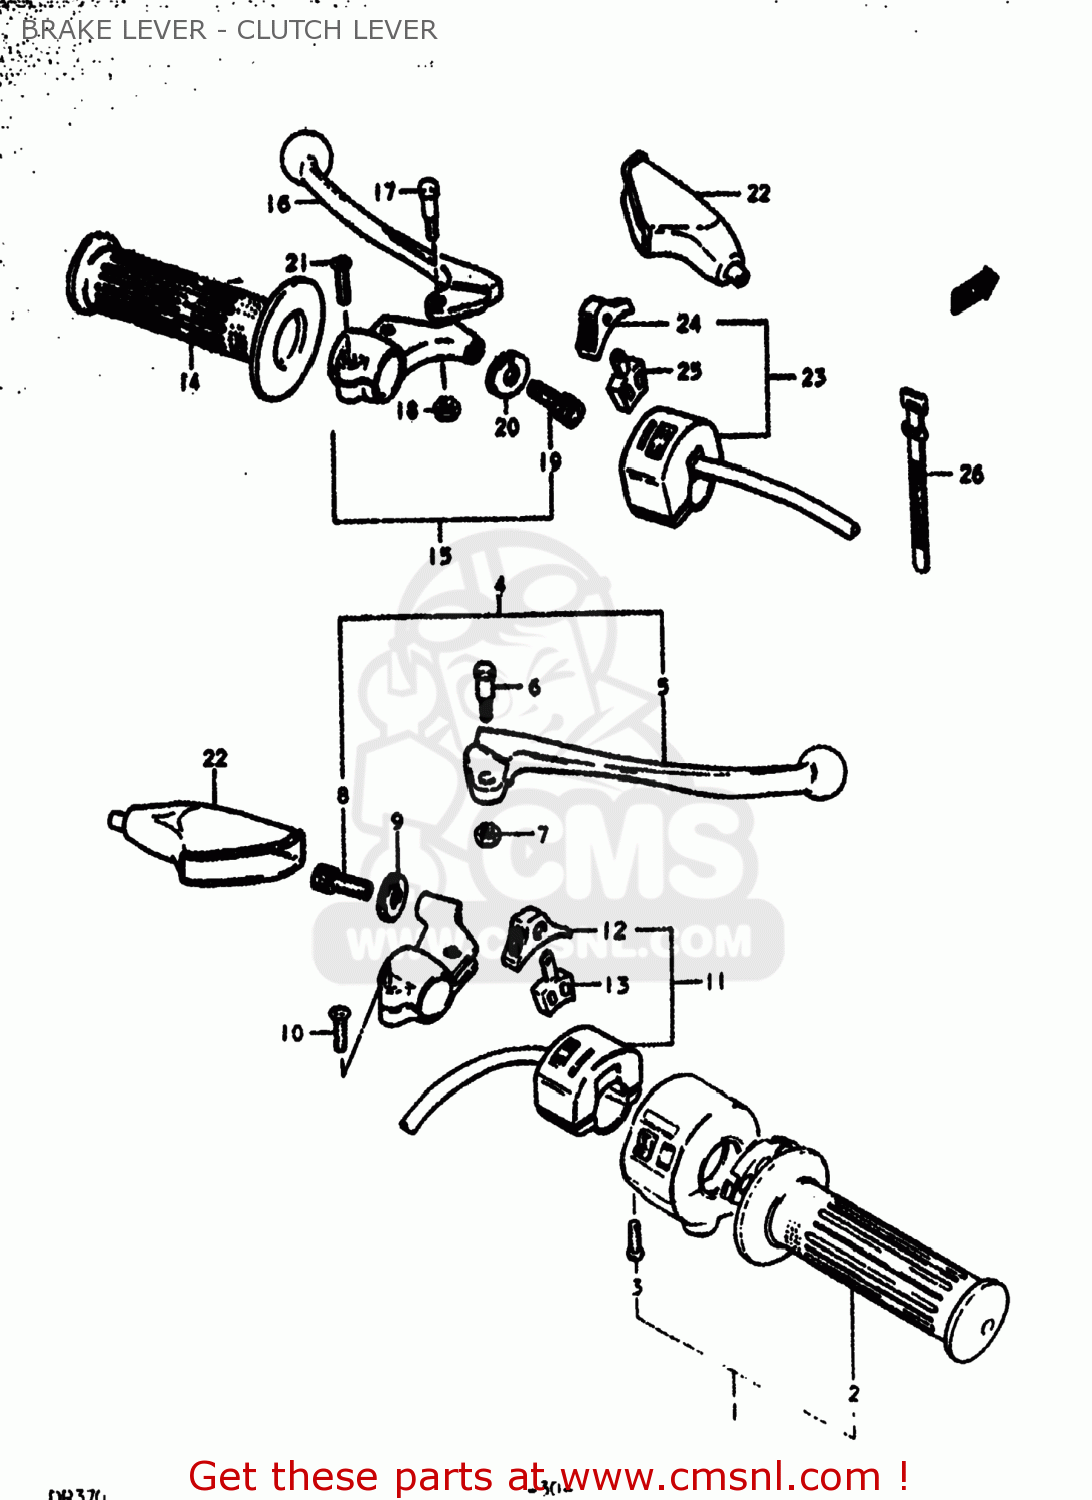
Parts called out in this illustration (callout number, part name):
1	CASE ASSEMBLY,THROTTLE
2	GRIP,THROTTLE
3	SCREW
4	LEVER ASSY,BRAKE
5	LEVER,BRAKE
6	BOLT,LEVER
7	NUT 6MM
8	ADJUSTER,CABLE
9	NUT,CABLE ADJUSTER
10	SCREW
11	SWITCH ASSEMBLY,LIGHTING
12	KNOB,LIGHTING & DIMMER
13	BLOCK,LIGHTING/DIMMER
14	GRIP,L
15	LEVER ASSEMBLY
16	LEVER,CLUTCH
17	BOLT,LEVER
18	NUT 6MM
19	ADJUSTER,CABLE
20	NUT,CABLE ADJUSTER
21	SCREW
22	COVER,CLUTCH LEVER
23	SWITCH,DIMMER
24	KNOB,HANDLE SWITCH
25	BLOCK,LIGHTING/DIMMER
26	CLAMP(L:120)
